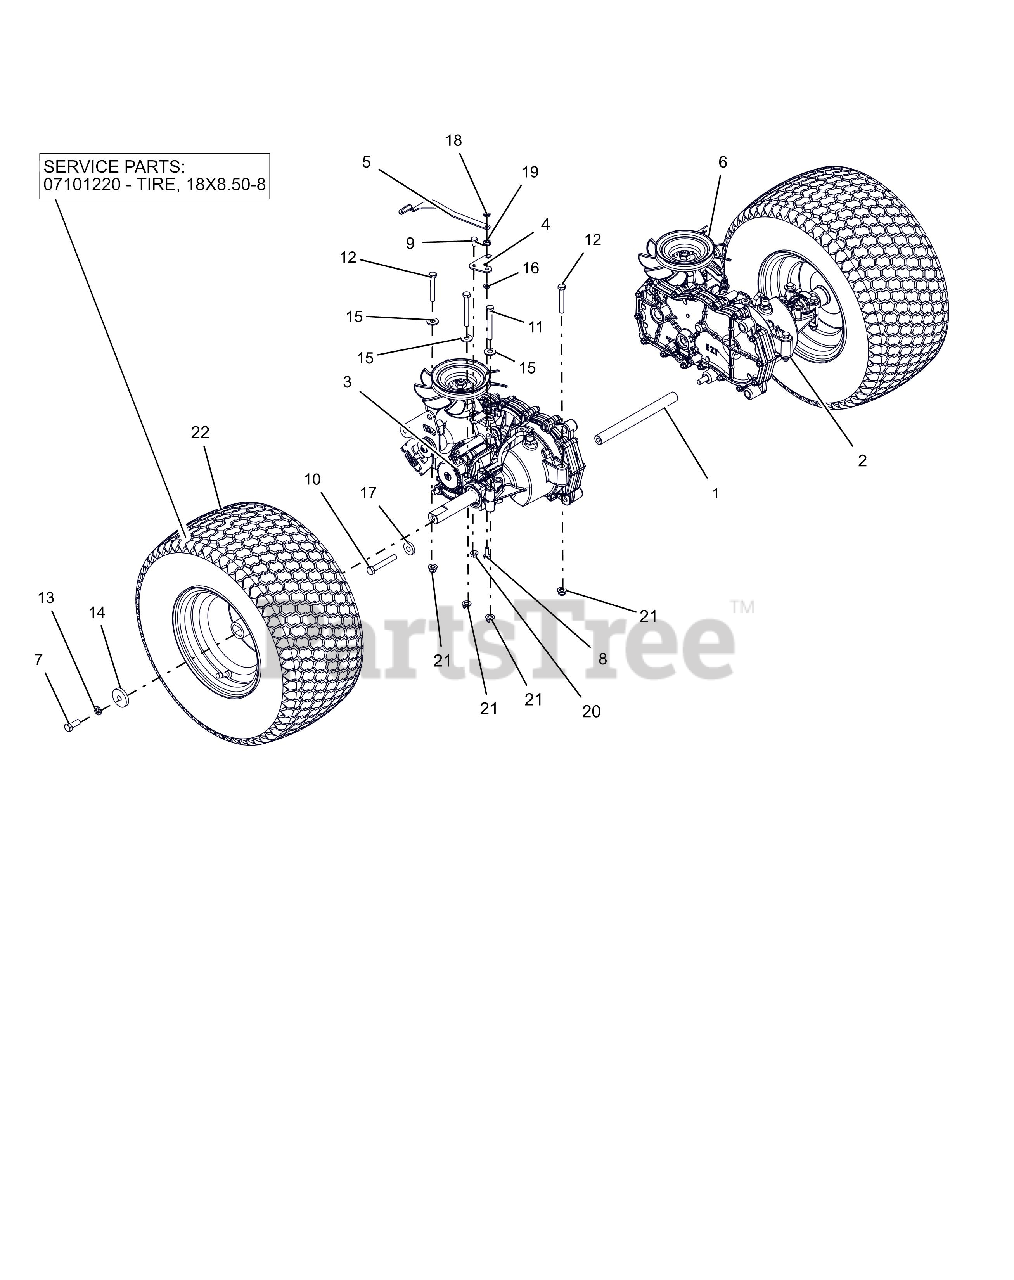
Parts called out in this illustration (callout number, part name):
1	ROD, TRANSAXLE BRACE
2	TRANSAXLE,LH EZT D-SHFT SHORT
3	TRANSAXLE,RH EZT D-SHFT SHORT
4	BRKT, DUMP VALVE EXTENSION
5	BRKT, DUMP VALVE RH
6	BRKT, DUMP VALVE LH
7	BLT-HEX .38-16X1.0 GR8 YZ EP30
8	@BLT-HEX .25-20X.75 GR5 YWZC
9	@BLT-HEX .25-20X.50 GR5 YWZC
10	@BLT-HEX .38-16X2.50 GR5 YWZC
11	@BLT-HEX .31-18X2.75 GR5 YWZC
12	@BLT-HEX .31-18X2.25 GR5 YWZC
13	@WSHR-LK .38X.094 REG YWZC
14	WSHR,FLT STL.406X1.50X.245YWZC
15	@WSHR-FL-STL.38X.875X.083 YWZC
16	WSHR-FL-STL .265X.50X.087YWZC
17	WSHR-FL-STL .406X1.00X.188 YWZ
18	NUT-LK-CTR JAM .25-20 YWZC
19	@NUT-SPNLK-FLG .25-20 YWZC
20	@NUT-LK-TOP-FLG .25-20 YWZC
21	@NUT-LK-NYL-FLG .31-18 YWZC
22	ASM, WHL/TIRE 18X8.50-8 DHUB
22	LAWN TIRE REAR, 4 PLY K500 18/8.50-8
